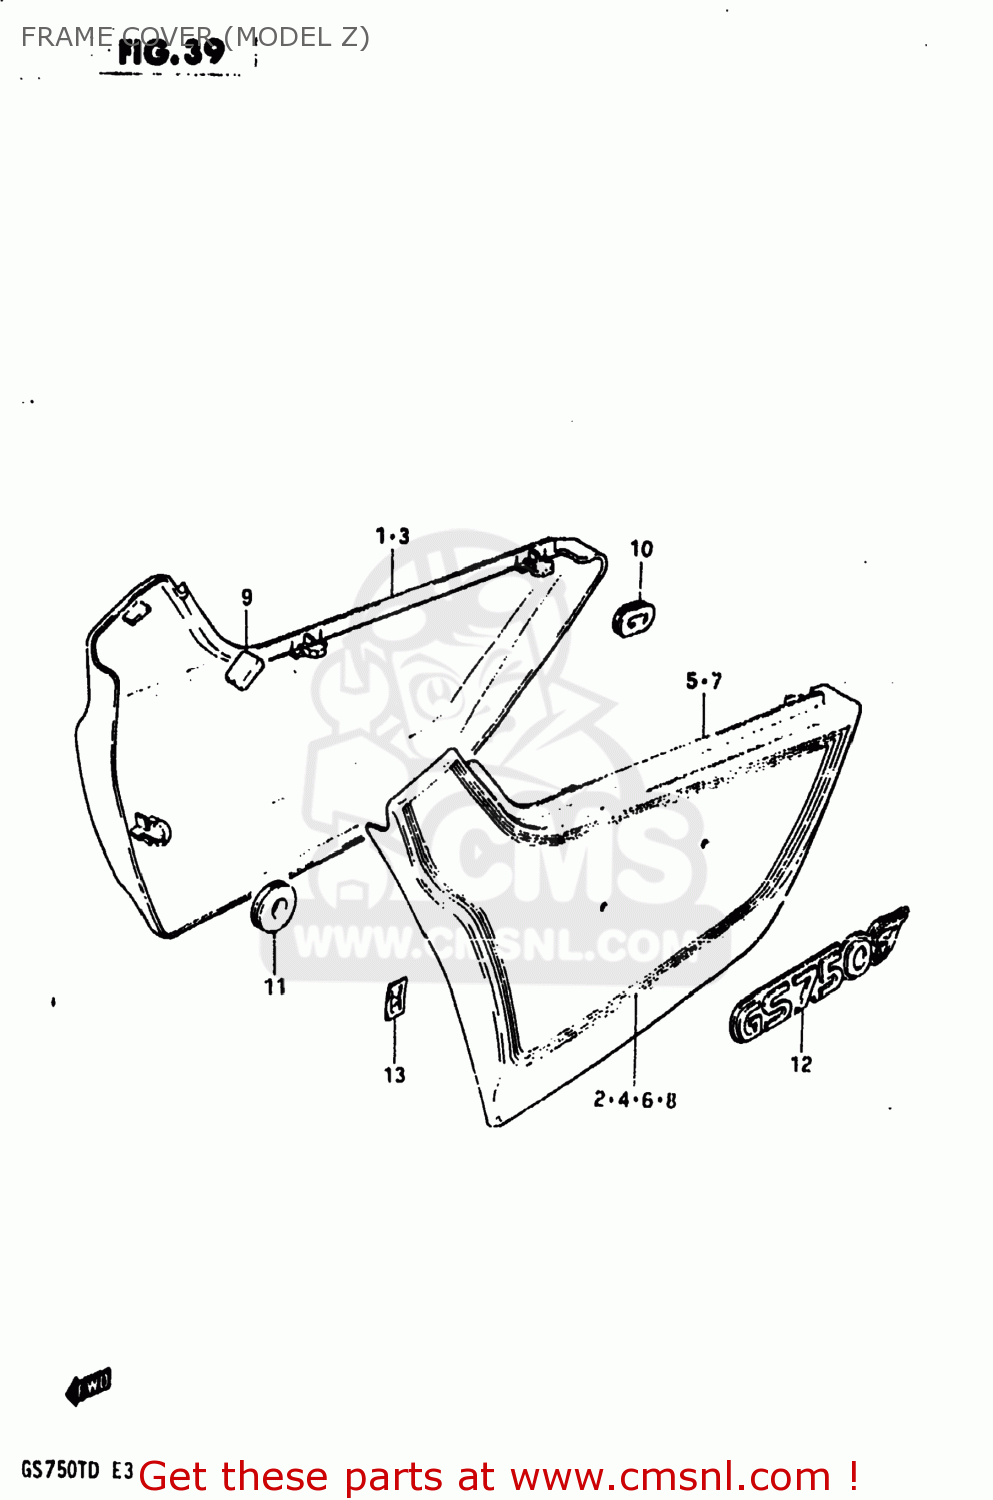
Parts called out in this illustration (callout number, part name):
1	COVER,FRAME,RIGHT
2	TAPE SET,FRAME COVER
3	COVER,FRAME,RIGHT
4	TAPE SET,FRAME COVER,RIGHT
5	COVER,FRAME,LEFT
6	TAPE SET,FRAME COVER
7	COVER,FRAME,LEFT
8	TAPE SET,FRAME COVER
9	CUSHION
10	CUSHION
11	CUSHION
12	EMBLEM,FRAME COVER
13	NUT
